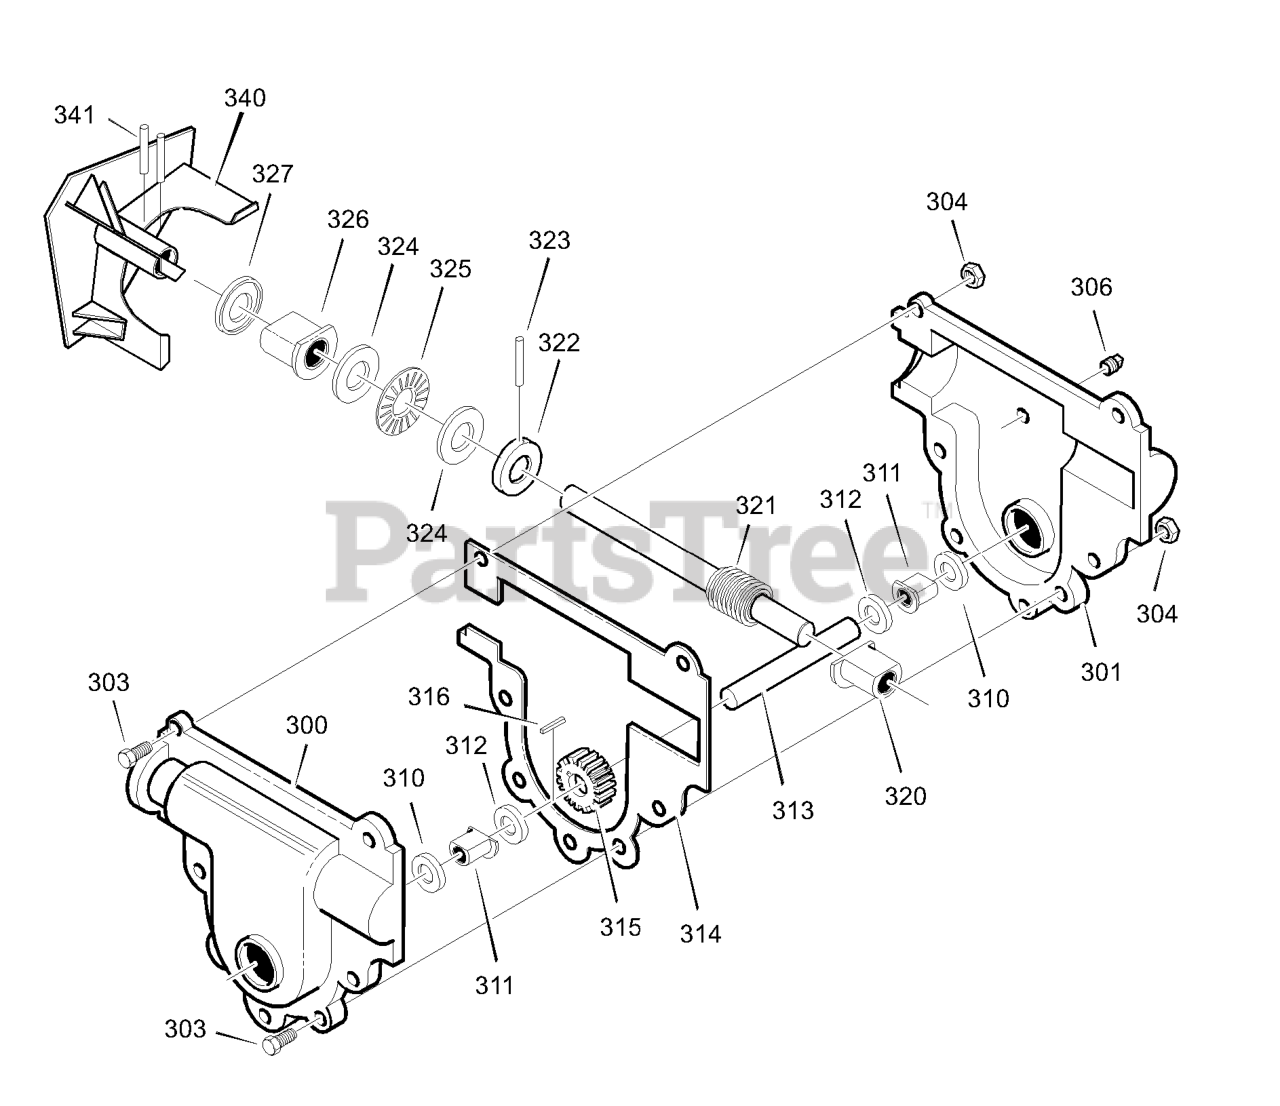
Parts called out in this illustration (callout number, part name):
300	CASE, GEAR, RH
301	CASE, GEAR, LH
306	SCREW
310	SEAL, OIL
311	BEARING, FL
312	WASHER, FLAT
313	SHAFT, OUTPUT
315	GEAR, WORM
316	KEY, WOODRUFF
320	BRNG, FL
321	SHAFT, INPUT
322	COLLAR, THRUST
323	PIN, SPRING
324	WASHER, FLAT
325	BRNG, ROLL
326	BRNG, FL
327	SEAL, OIL
340	IMPELLER ASSEMBLY
341	PIN, SPRING
